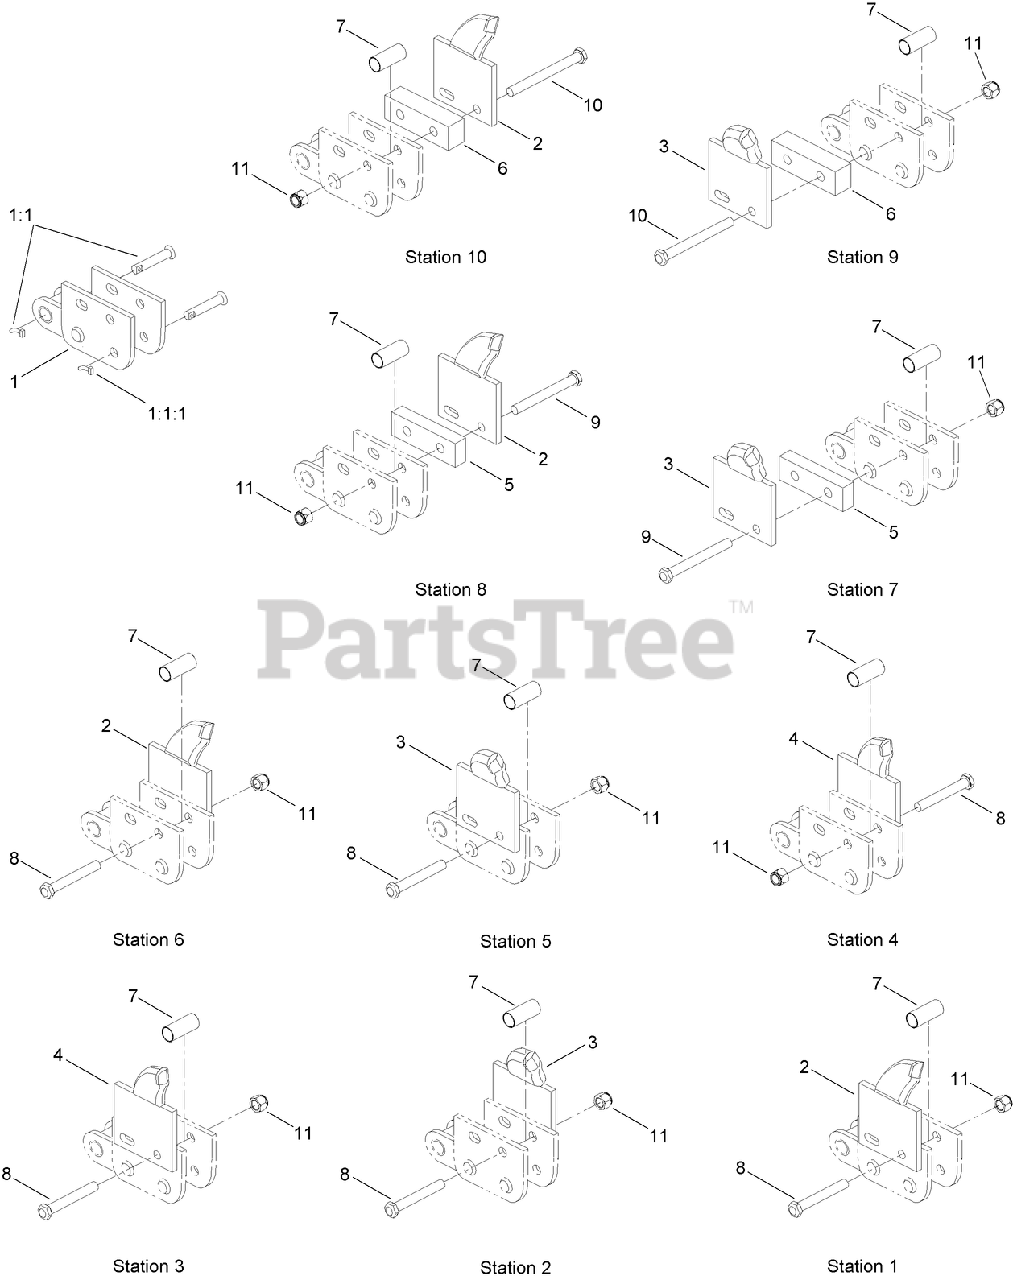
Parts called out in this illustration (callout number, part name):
1	CHAIN REPAIR LINK ASM
1:1	NOTCHED PIN AND KEEPER ASM
1:1:1	PIN-KEEPER
2	TOOTH-TERMINATOR, LH
3	TOOTH-TERMINATOR, RH
4	TOOTH-TERMINATOR, STRAIGHT
5	SPACER-FLAT (.500 Inch)
6	SPACER-FLAT (1.00 INCH)
7	SPACER-TUBE, OUTSIDE MOUNT
8	BOLT-HH
9	BOLT-HH
10	BOLT-HH
11	NUT-LOCK
